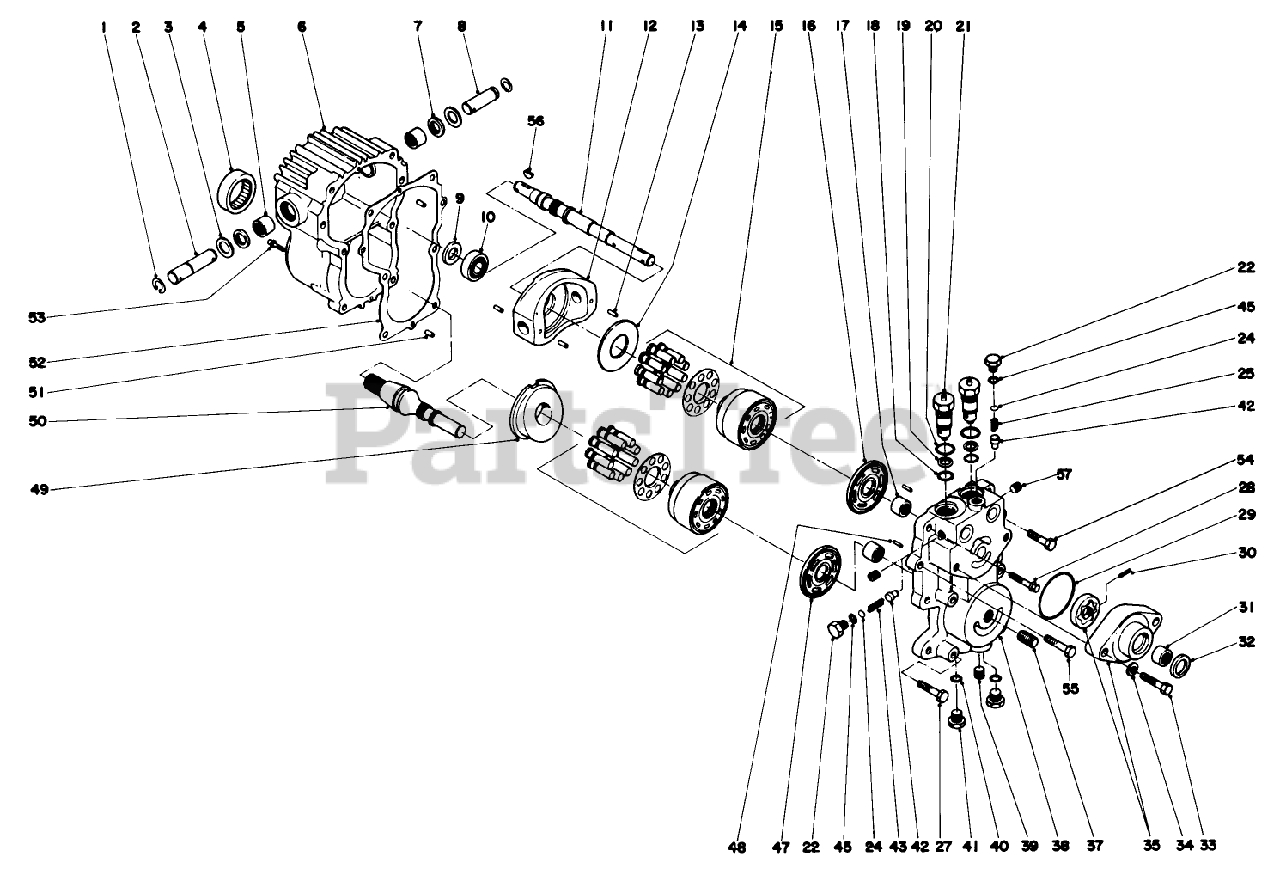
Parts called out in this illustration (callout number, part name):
1	RING-RETAINING
2	SHAFT-TRUNNION
3	WASHER-FLAT
4	BEARING-ROLLER
6	Housing
7	SEAL-LIP
8	SHAFT-TRUNNION
11	SHAFT-PUMP
13	PIN-SPRING
17	BEARING-NEEDLE
18	O-RING
19	RING-BACK UP
20	O-RING
22	PLUG-HH
24	PACK-SHIM
25	SPRING-VALVE
27	SCREW-HH
28	CAPSCREW
29	O-RING
32	SEAL-LIP
34	WASHER
37	UNION-FILTER
40	"O" Ring
41	PLUG-THREADED
43	SPRING-VALVE
45	O-RING
47	PLATE-VALVE, MOTOR
48	PIN-DOWEL
52	GASKET
54	SCREW-HH
55	SCREW-HH
56	KEY-WOODRUFF
57	PLUG-PIPE
